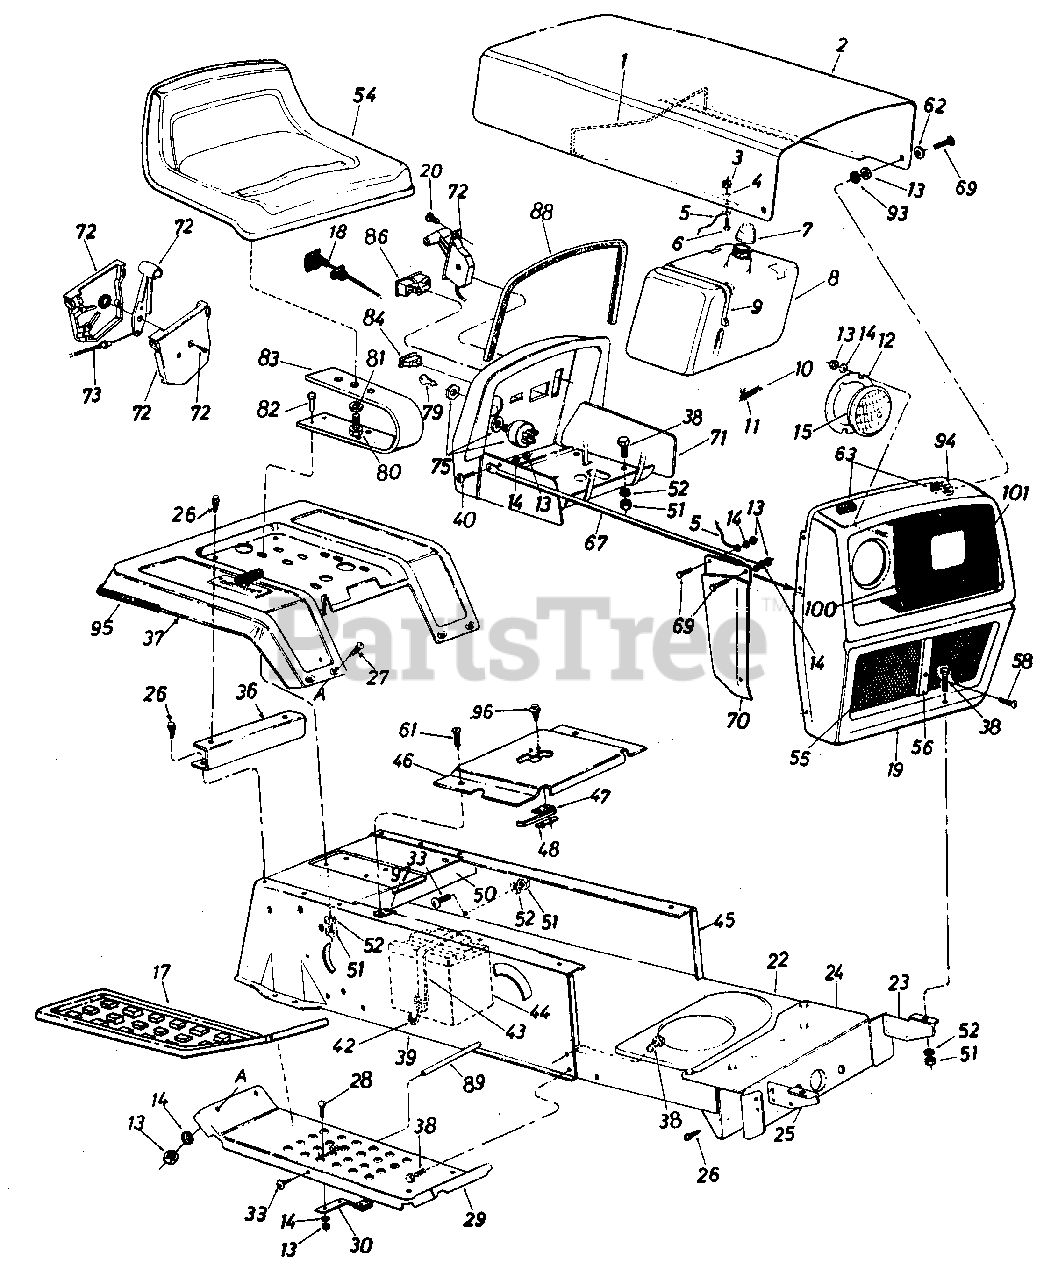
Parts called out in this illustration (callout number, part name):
3	Hex Sems Nut #10-24 Thd.
5	Hood Stop 7" Lg.
6	Truss Hd. Scr. #10-24 x 1/2"
7	Fuel Cap Gauge
8	Fuel Tank
9	Tie Strap
10	Fuel Line
12	Headlight Retainer
13	Hex Nut 1/4-20 Thd.
14	L-Wash. 1/4" I.D.
15	Headlight
18	Choke Control 29" Lg.
19	Grille Ass'y.
20	Truss Mach. AB-Tap Scr. #10 x .50" Lg.
22	Lower Frame
23	Grille Mount Brkt. L.H.
24	Front Pivot Brkt.
25	Grille Mount Brkt. R.H.
26	Hex Wash. Hd. AB-Tap Scr. 5/16 x .75" Lg.
27	Carriage Bolt 1/4-20 x .50"*
28	Carriage Bolt 1/4-20 x .62"
29	Running Board
30	Blade Brake Ass'y.
33	Truss Mach. Scr. 5/16-18 x .75" Lg.
36	Fender Mount Brace
37	Fender
38	Hex Bolt 5/16-18 x .75" Lg.
39	R.H. Side Frame
40	Hex Bolt 1/4-20 x .62" Lg.
42	Battery Strap Hook
43	Battery Hold Down Strap
44	12-V Battery
45	L.H. Side Frame
46	Shift Cover
47	Reverse Safety Switch
48	Insulator Nut Plate
50	Hitch Plate
51	Hex Nut 5/16-18 Thd.
52	L-Wash. 5/16" I.D.
54	Seat Ass'y.
56	Moulding
58	Hex Wash. F-Tap Scr. #8 x .38" Lg.
61	Truss Mach. Tap Scr. #10 x .50" Lg.
62	Fl-Wash. .281 I.D. x .73 O.D.
63	Foam Strip 3/8 x 1-1/8 x 1-1/2
67	Grille Support Rod
69	Truss Hd. Scr. 1/4-20 X .75"
70	R.H. Grille Side Panel
71	Dash Panel Ass'y.
72	Throttle Control Box Ass'y.
73	Throttle Control Wire
75	Ignition Switch
79	Ignition Key
80	Hex Bolt 1/2-13 X 1.0" Lg.
81	L-Wash. 1/2" I.D.
82	Hex Bolt 5/16-18 x 1.0"
83	Seat Spring 5.5" High
84	Light Switch
86	Ammeter
88	Molding Strip 27" Lg.
89	Running Board Rod
93	Rubber Wash. 1/2" I.D. x 1.0 O.D. x .25"
94	Hex Sems Ins. L-Nut 1/4-20 Thd.
95	Trim Strip 81"
96	Hex Wash. Hd. AB-Tap Scr. #8 x .50" Lg.
97	Speed Nut #10Z
101	Truss Scr. #10-24 x .62" Lg.
